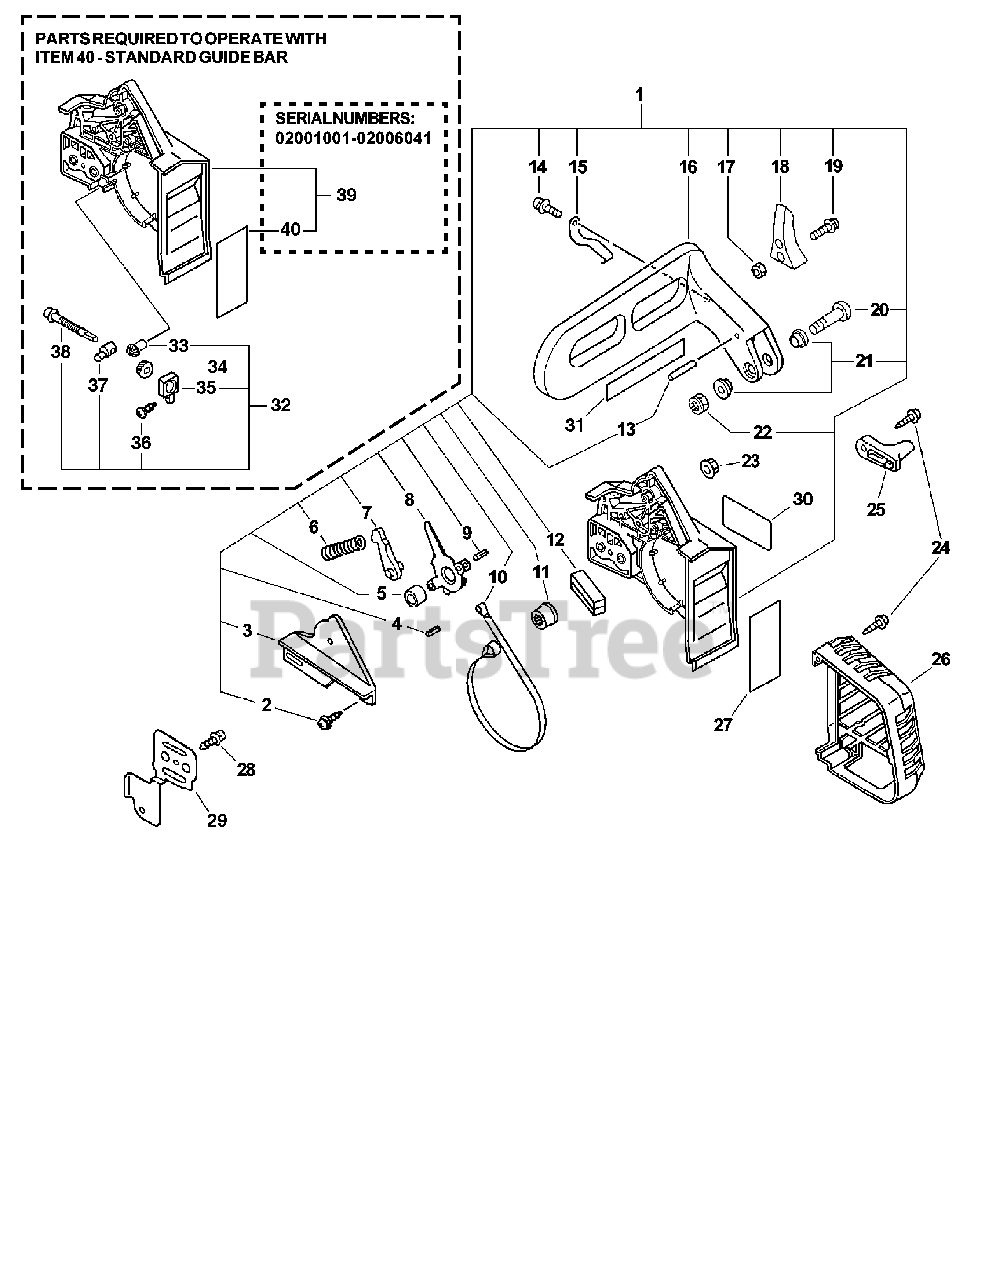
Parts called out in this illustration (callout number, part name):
1	CHAIN BRAKE ASSY
2	SCREW - 4X12 -- TAPPING
3	COVER, BRAKE - GRAY
4	PIN - SPRING -- 2.5X12
5	SPACER - 8
6	SPRING, BRAKE
7	STOPPER, BRAKE
8	LEVER, BRAKE
9	PIN - SPRING -- 4X8
10	BAND, BRAKE
11	ADJUSTER, BRAKE BAND
13	ROLLER - 4X23.8
14	SCREW - 4X10
15	SPRING, RETURN
16	LEVER, BRAKE - ORANGE
18	WEIGHT, BRAKE
19	SCREW - 4X20
20	SCREW - 5X32
22	LOCKNUT - 5
23	NUT - 6 -- FLANGE
24	SCREW - 5X20 -- TAPPING
25	CATCHER, CHAIN
26	COVER, EXHAUST
27	DEFLECTOR, HEAT
28	SCREW - 4X10
29	PLATE, GUIDE - OUTER
30	LABEL - MODEL CS-346
31	LABEL - BAR & CHAIN -- US
31	LABEL - BAR & CHAIN
32	SIDE ADJUSTER KIT
33	GEAR - PINION
34	GEAR - BEVEL
35	BRACKET, TENSIONER
36	SCREW - 4X12 -- TAPPING
37	TENSIONER, CHAIN
38	SCREW, TENSIONER
39	GUARD, SPROCKET - GRAY
40	DEFLECTOR, HEAT
